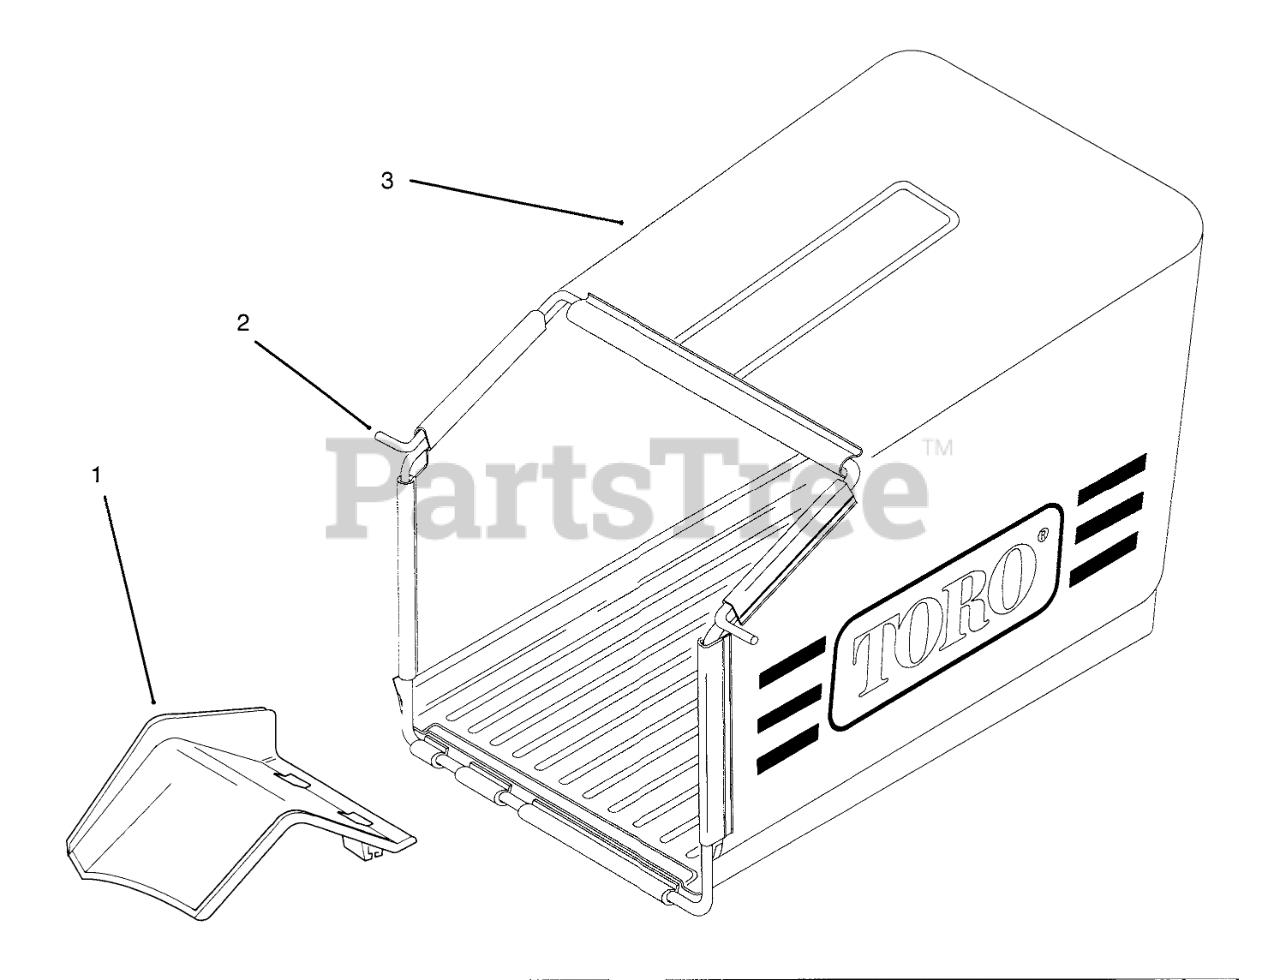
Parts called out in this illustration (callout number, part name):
1	REMOVER-BAG, GRASS
2	FRAME-BAG
3	BAG-GRASS
